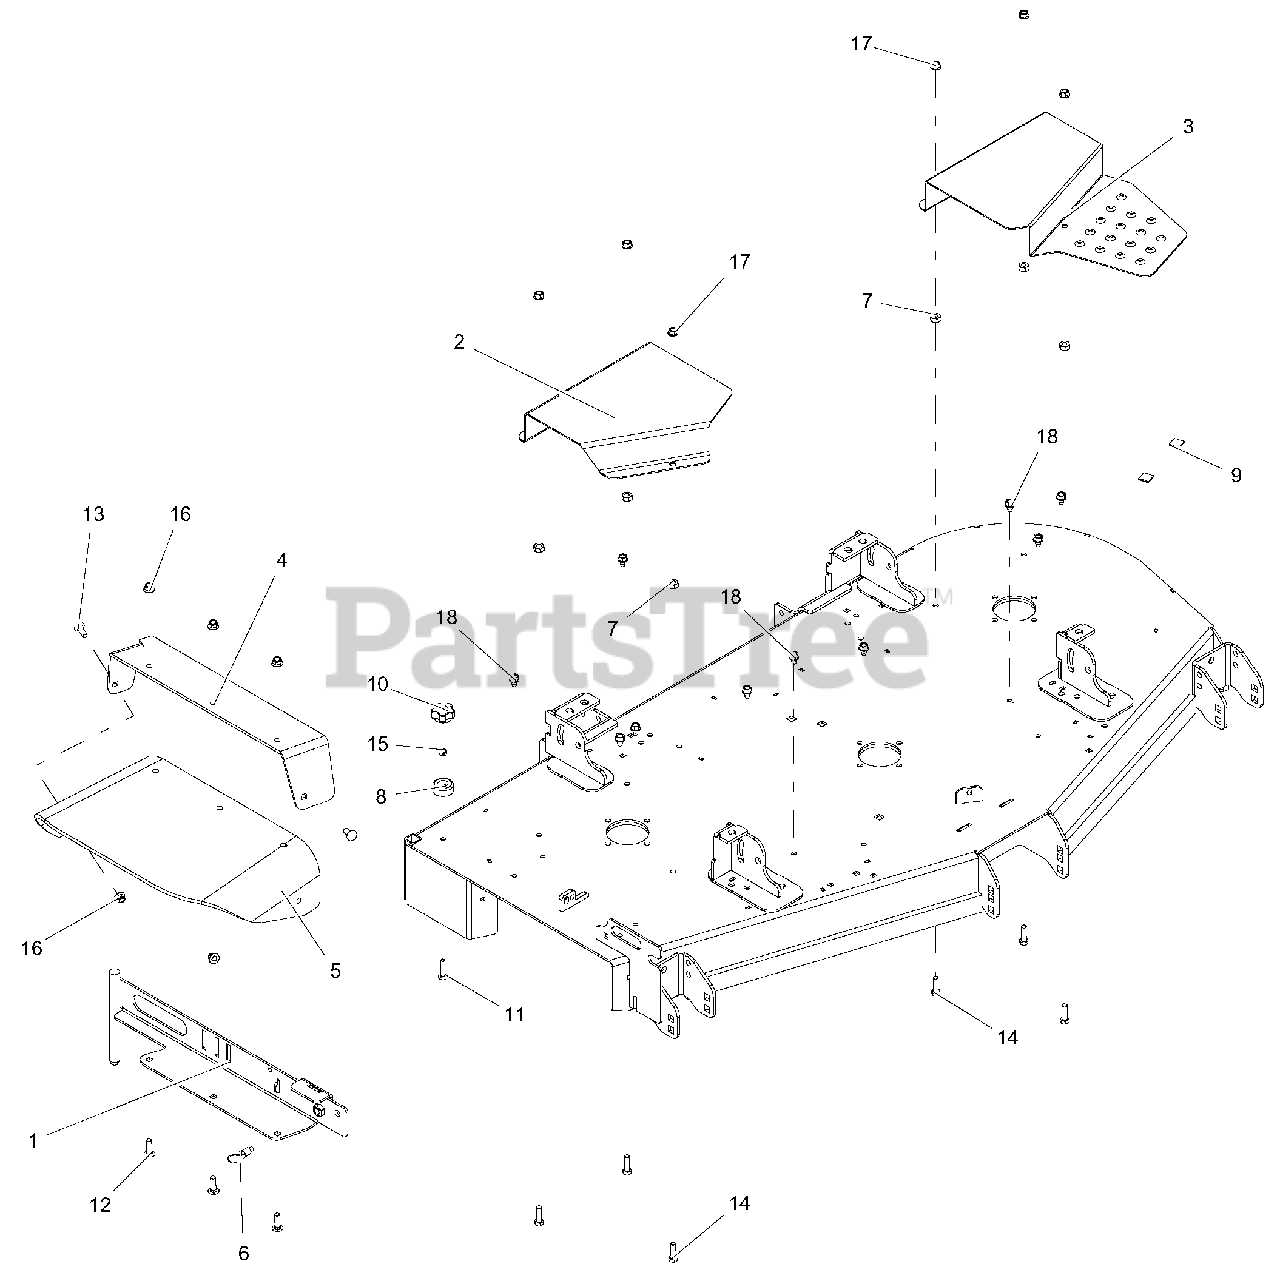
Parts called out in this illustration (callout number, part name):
1	WLDMT, 52"-60" DISCH CHUTE MTG-RED
2	GUARD, 60"-66" RH DECK BELT-RED
3	GUARD, 60" LH DECK BELT-W/STEP-RED
4	DISCHARGE CHUTE SUPPORT W/SAFETY DECAL-RED
5	CHUTE, RUBBER DISCHARGE
6	PULL PIN,.50-13THDX.310 PLNGR
7	NUT-HEAVY HEX .38-16 YWZC
8	BUMPER, RECESSED 1.50 X .63 W/.31 HOLE
10	KNOB, CLAMPGIN
11	BLT-RDHDSQNK .31-18X1.50 G5 YWZC
12	BLT-RDHDSQNK .38-16X1.25 G5 YWZC
13	BLT-RDHDSQNK .38-16X1.00 G5 YWZC
14	BLT-HEX .38-16X1.25 GR5 YWZC
15	NUT-LK-CTR .31-18 YWZC
16	NUT-LK-NYL-FLG .38-16 YWZC
17	@NUT-SPNLK-FLG .375-16 YWZC
18	SCR-TAP .38-16X.50 HWH TR YWZ
